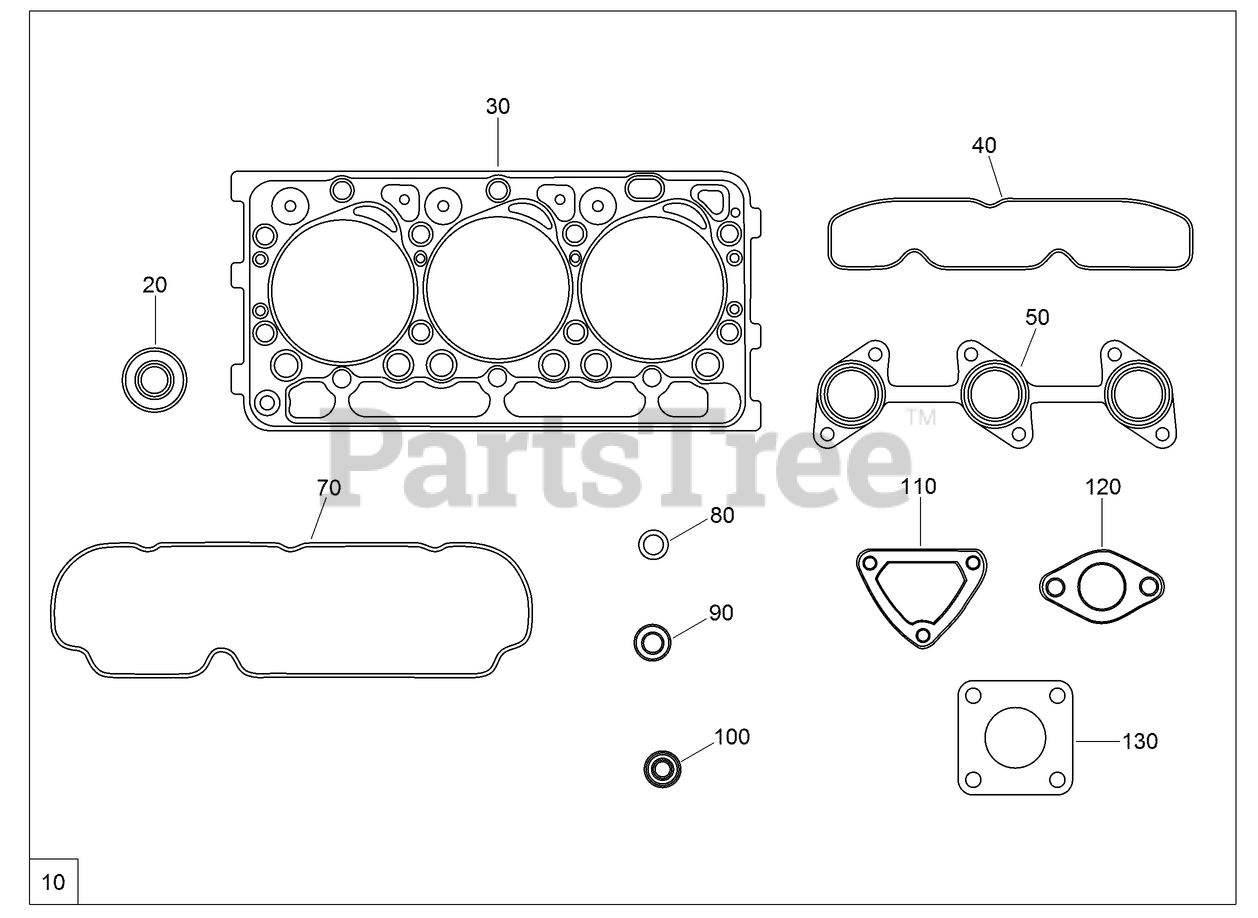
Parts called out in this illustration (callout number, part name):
10	UPPER GASKET KIT
20	SEAL-STEM, VALVE
30	GASKET-HEAD, CYLINDER
40	GASKET-MANIFOLD, INTAKE
50	GASKET-MANIFOLD, EXHAUST
70	GASKET-COVER, HEAD
80	O-RING
90	GASKET
100	SEAL-HEAT
110	GASKET-FLANGE, WATER
120	GASKET-THERMOSTAT
130	GASKET-MUFFLER
